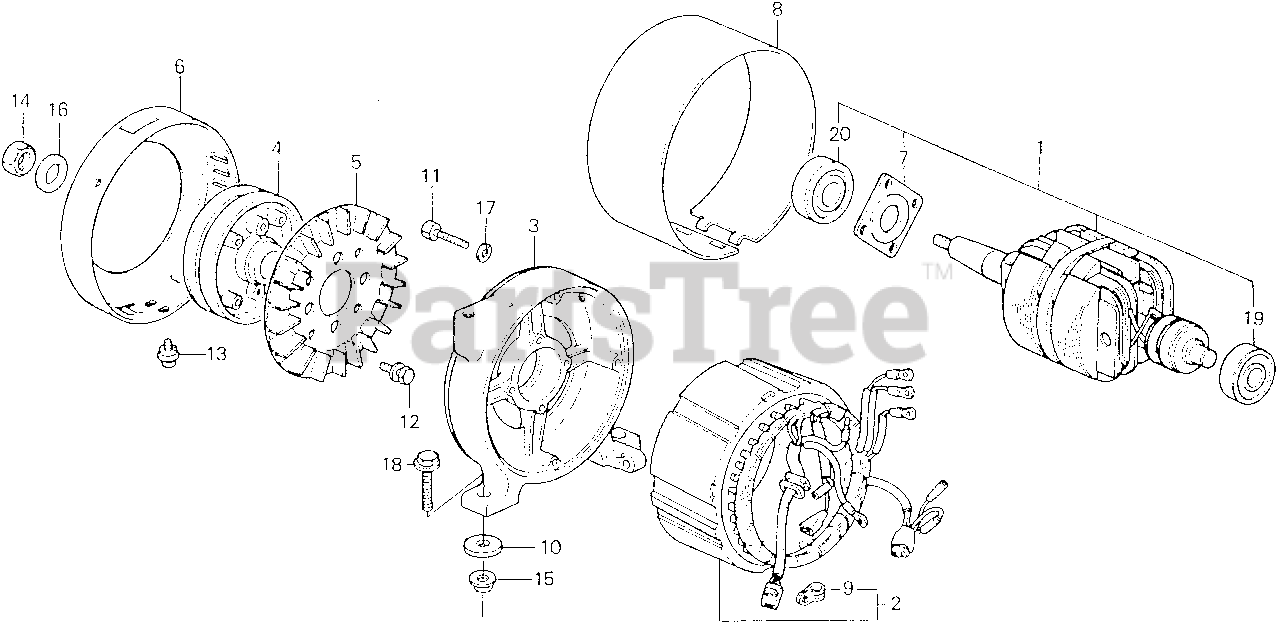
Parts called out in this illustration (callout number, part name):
2	STATOR
2	STATOR (NOT AVAILABLE)
3	HOUSING, FR. *NH31* (MCKINLEY WHITE)
4	PULLEY, ALTERNATOR (135MM) *NH1* (BLACK)
6	COVER, FAN *NH31* (MCKINLEY WHITE)
7	PLATE, BEARING SETTING
8	COVER, STATOR *NH31* (MCKINLEY WHITE)
9	CLIP, WIRE
10	WASHER, EX. MANIFOLD
11	BOLT, HEX. (5X32) (NOT AVAILABLE)
12	BOLT-WASHER (6X12)
13	SCREW-WASHER (5X10)
14	NUT, HEX. (18MM) (NOT AVAILABLE)
15	NUT, FLANGE (10MM)
16	WASHER, FLAT (18MM) (NOT AVAILABLE)
17	WASHER, SPRING (5MM)
18	BOLT, FLANGE (10X32)
19	BEARING, RADIAL BALL (6304UU)
20	BEARING, RADIAL BALL (6306UU)
